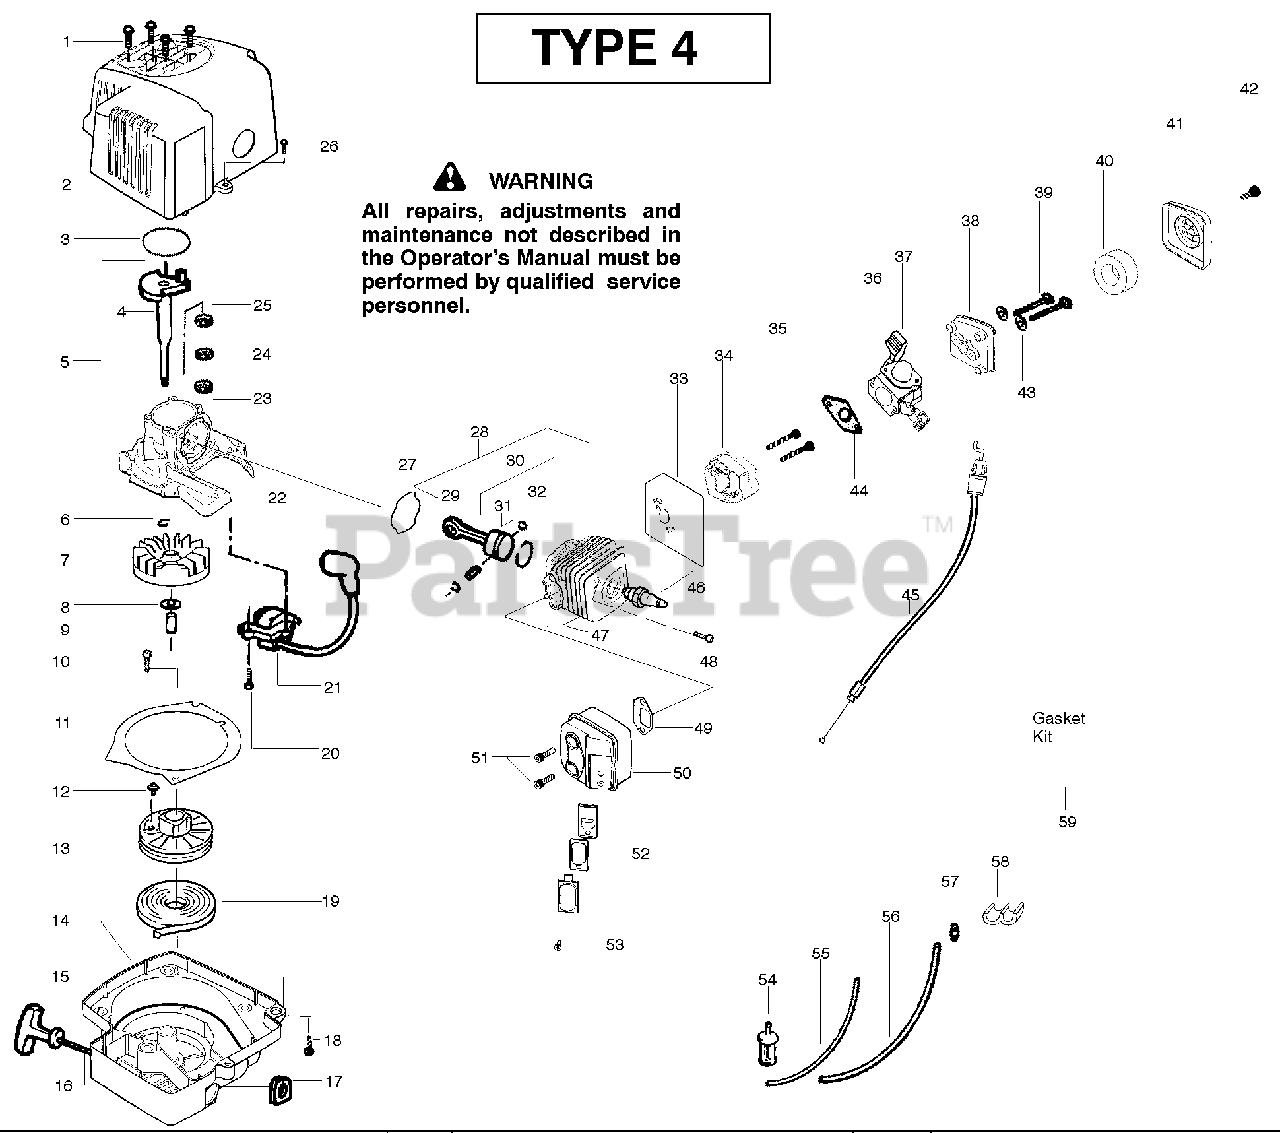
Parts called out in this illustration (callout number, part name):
2	Assy-Shroud/H'shield
3	O-Ring-C'case (kit)
4	Assy-Crankshaft
5	Assy-C/case-C/shaft
6	Ring-Retainer-C'shaft
7	Assy-Flywheel
8	Washer-Flat
9	Spacer-Flywheel
11	Plate-Baffle
13	Kit-Starter Pulley
14	Assy-Fan Housing
15	Handle-Starter
16	Kit-Rope
17	Grommet-Ignition Module
18	Screw-(f/hsg to shrd)
19	Spring-Starter
21	Ignition Module
22	Assy-Crankcase
23	Bearing-Outer
24	Seal-Crankcase
25	Bearing-Inner
27	Seal-Cylinder (kit)
28	Kit-Piston/Rod Assy.
29	Assy-Connecting Rod
30	Kit-Piston
31	Retainer-Piston Pin
32	Ring-Piston
33	Gasket-Carb. Adapt.(kit)
34	Adapter-Carburetor
36	Kit-Carburetor Ass'y. (C1U-W13A)
37	Kit-Choke Lever
40	Air Filter Foam
41	Air Filter Cover
43	Washer
44	Gasket-Carburetor(kit)
45	Assy-Throttle Cable
46	Spark Plug(RCJ-6Y)
47	Cylinder
49	Gasket-Muffler (kit)
50	Kit-Muffler
51	Bolt-Muffler
52	Kit-Spark Arrestor
54	Assy-Pick-up
55	Kit-Fuel Line(small)
56	Kit-Fuel Line(large)
57	Fitting-Fuel Line
58	Clip-Retainer
59	Kit-Gasket
